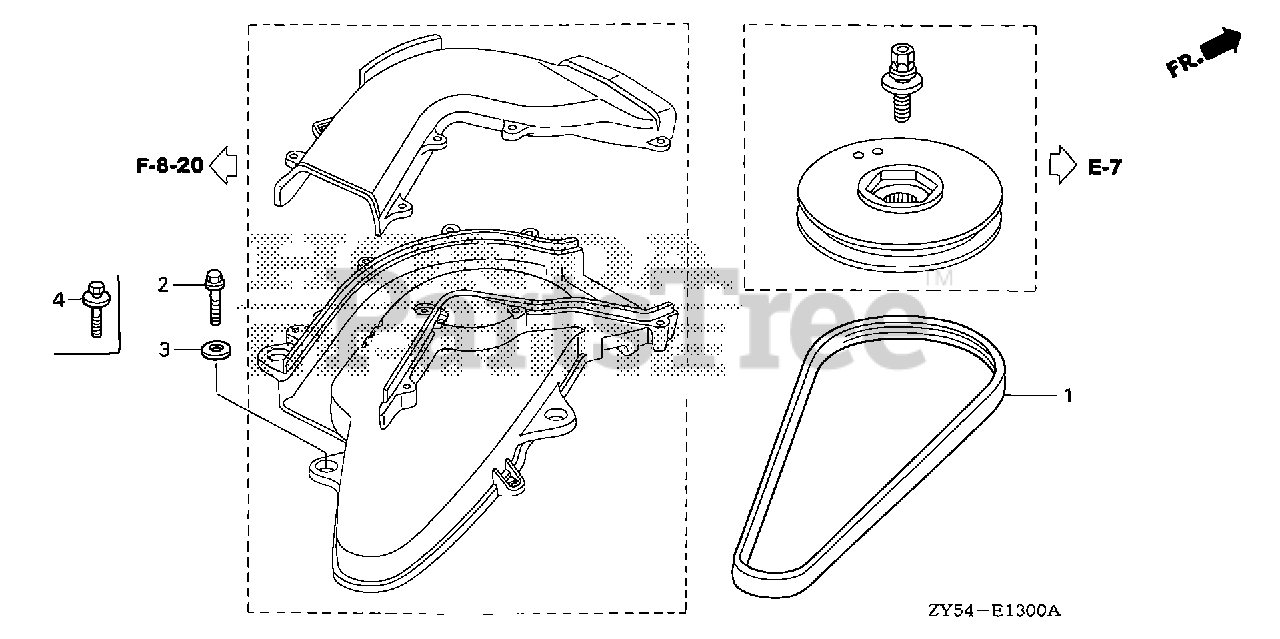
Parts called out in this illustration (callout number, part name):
1	BELT, ALTERNATOR (4PK810)
2	BOLT, FLANGE (6X25)
3	WASHER, PLAIN (6MM)
4	BOLT-WASHER (6X25)
